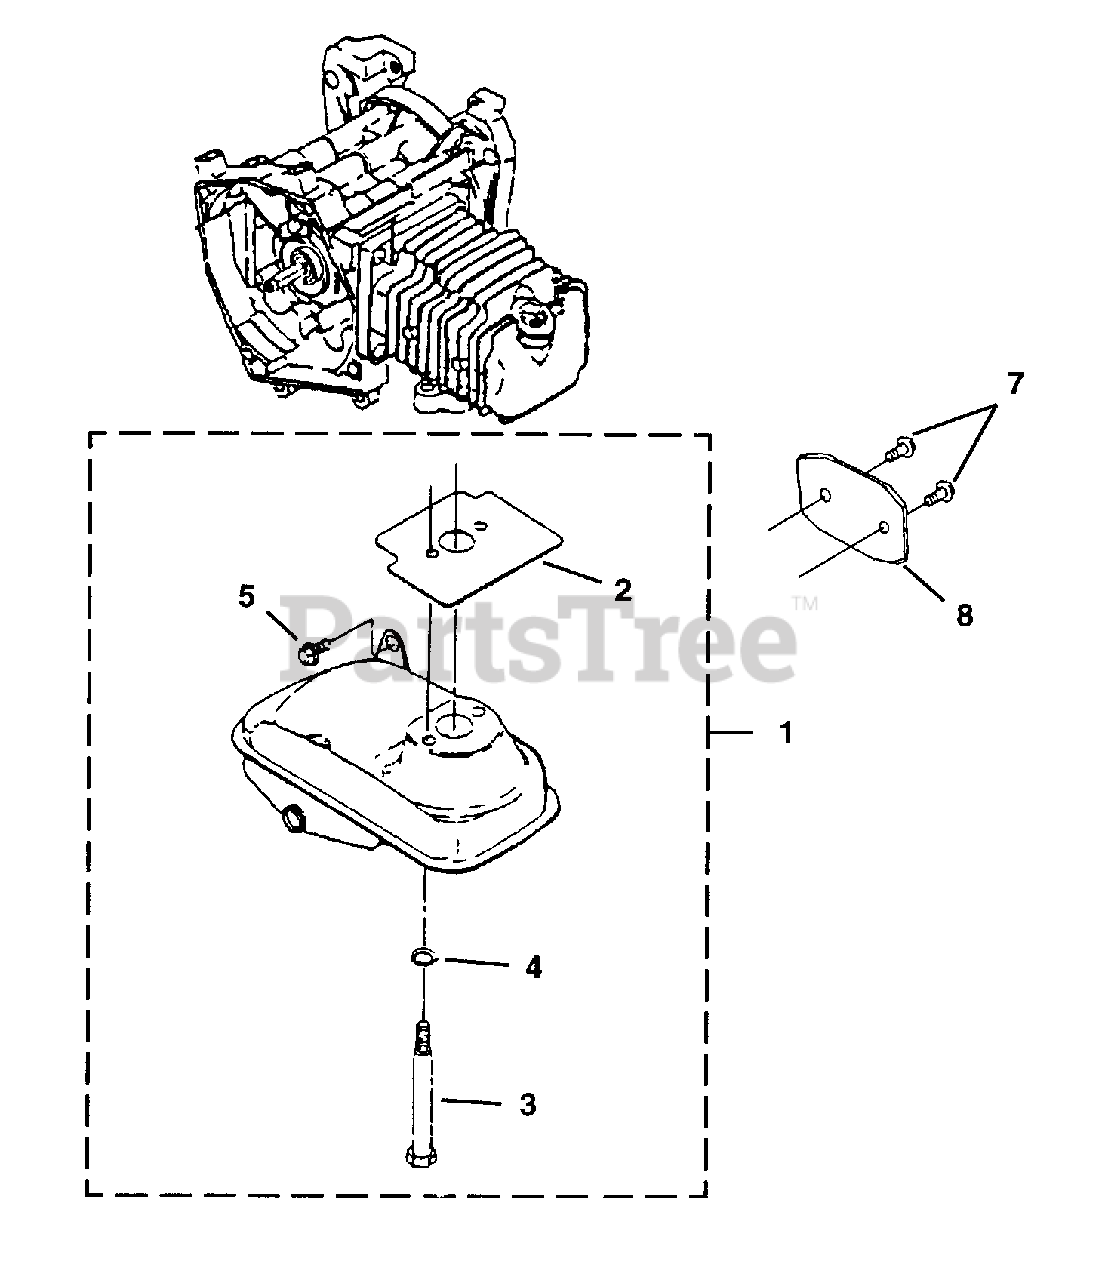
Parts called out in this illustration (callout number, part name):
1	MUFFLER ASSEMBLY
2	GASKET-Muffler
3	BOLT-Muffler (M6 x 13)
4	WASHER (M6)
5	BOLT ASSEMBLY (M6 x 16 W SW)
6	PROTECTOR
